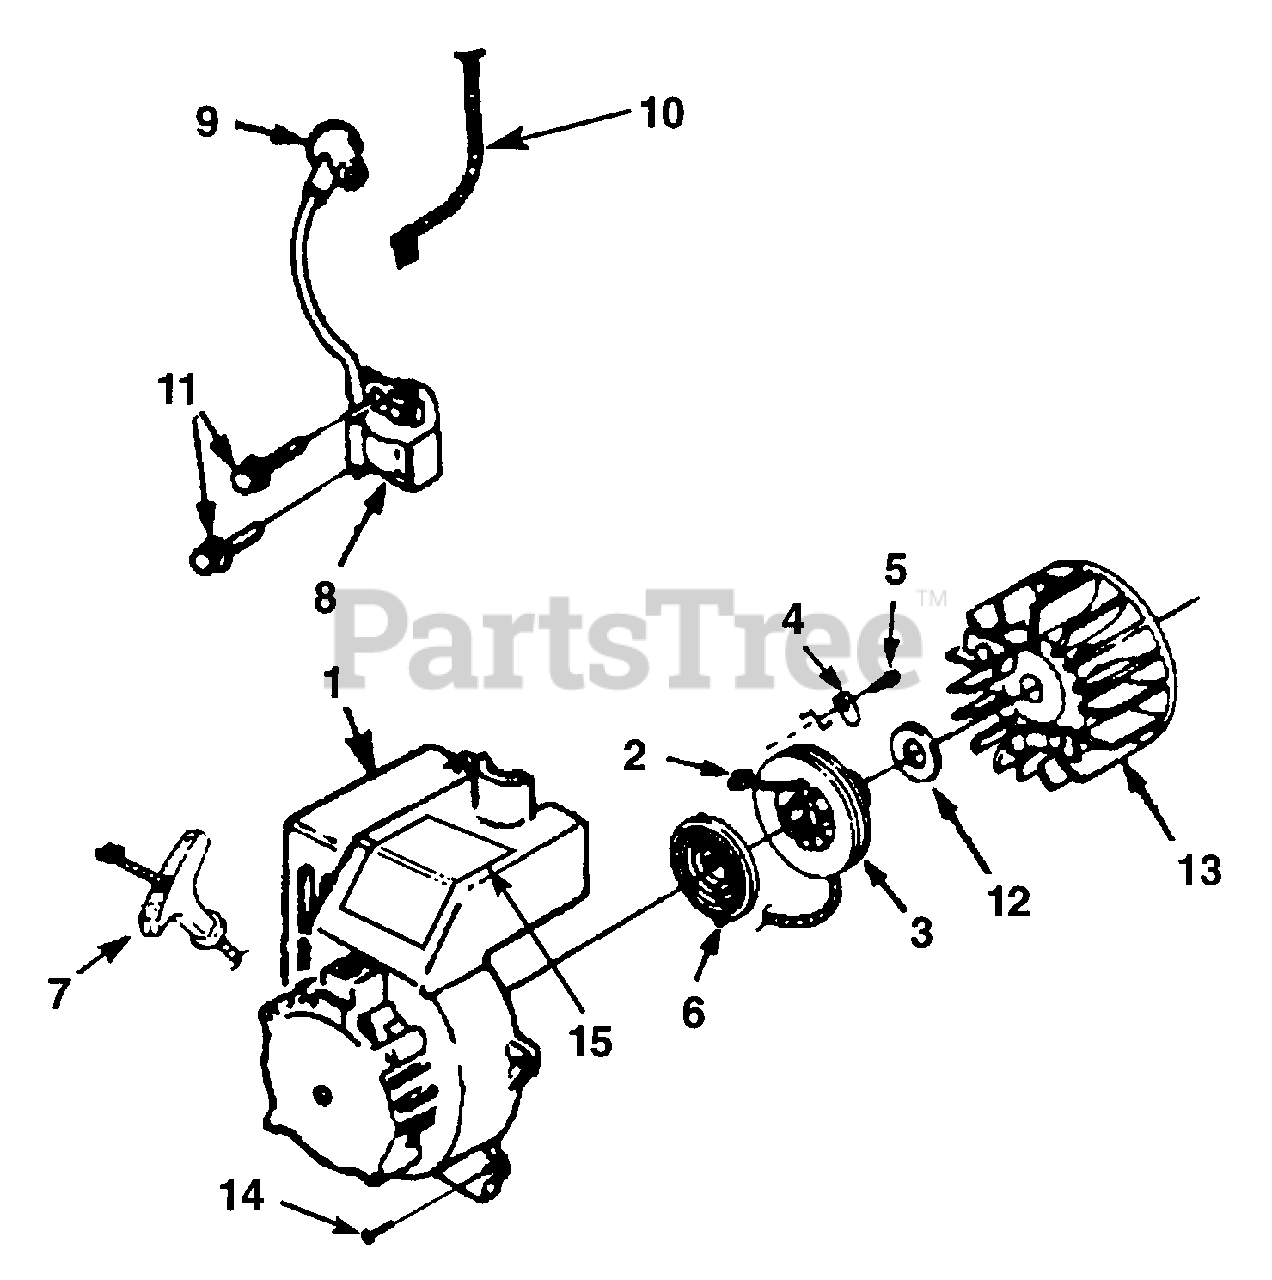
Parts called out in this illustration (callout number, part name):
1	Starter/Engine Housing
2	Starter Rope (42")
3	Starter Pulley
4	Retaining Bracket
5	Screw-Plastite (10 X 1/2")
6	Spring & Container
7	Starter Grip
8	Ignition Module
9	Terminal & Cover
10	Electrical Lead
11	Screw-Thread Forming (8-32 X 1")
12	Flat Washer
13	Rotor & Starter Pawls
14	Screw-Thread Forming (10-24 X 3/4")
15	Model Decal
